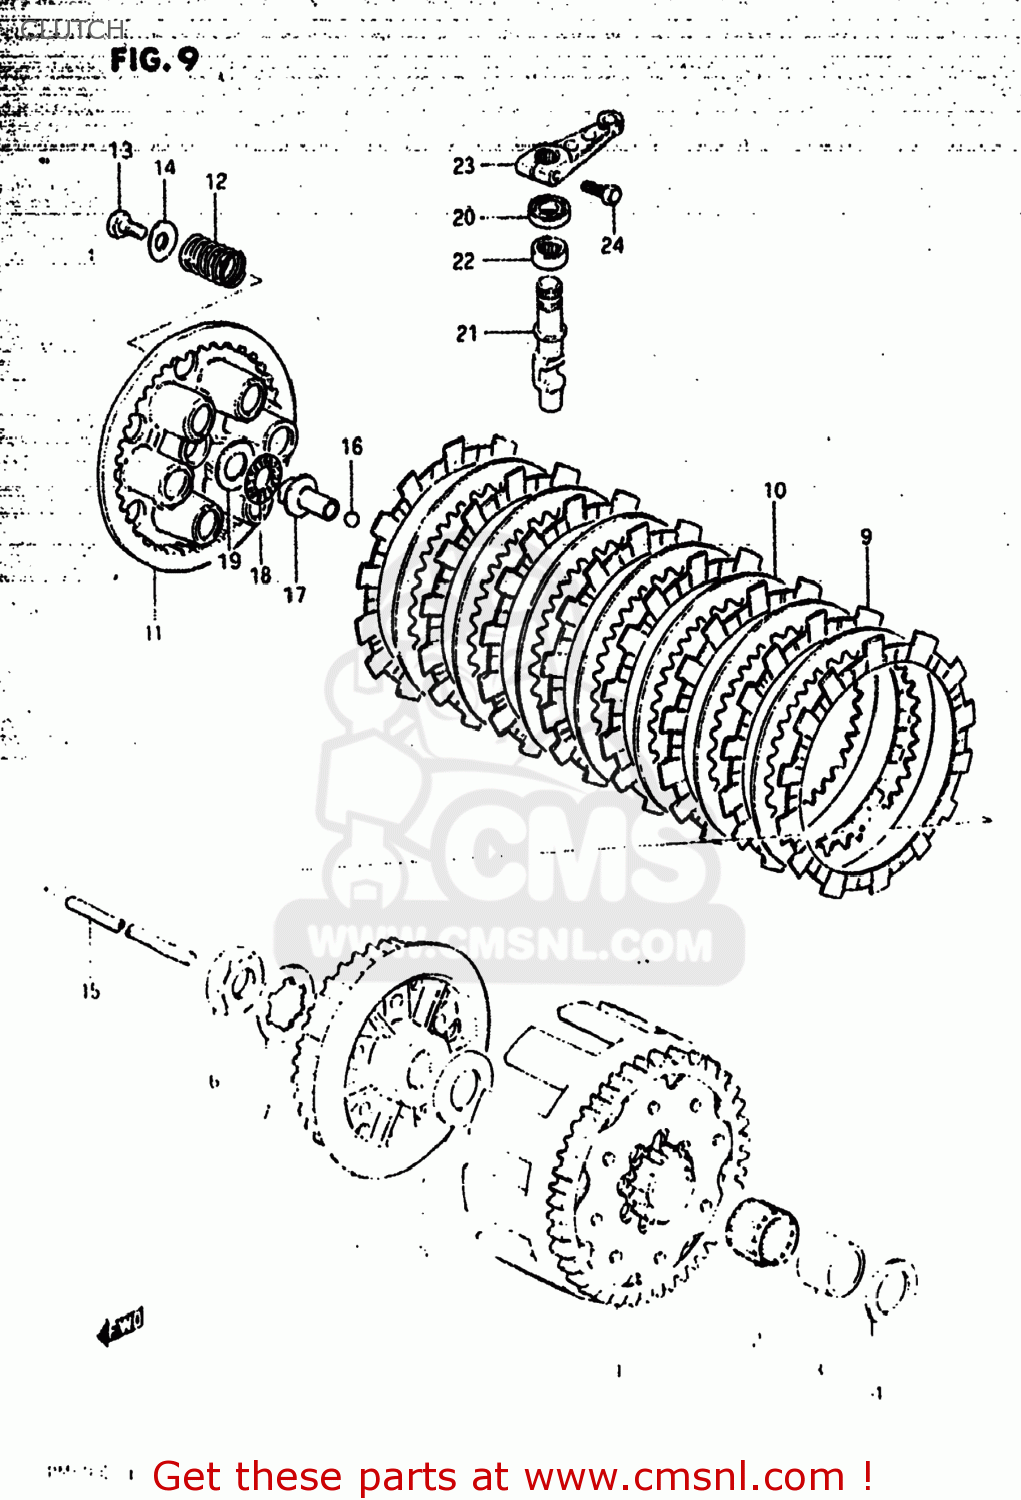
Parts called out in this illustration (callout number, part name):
1	GEAR ASSEMBLY,PRIMARY DRIVE
2	BEARING(28X33X27)
3	SPACER(22X28X27)
4	WASHER
5	HUB,CLUTCH SLEEVE
6	NUT
7	WASHER,LOCK
8	WASHER
9	PLATE,CLUTCH DRIVE (MCA)
10	PLATE,CLUTCH DRIVEN (NAS)
11	DISC,CLUTCH PRESSURE
12	SPRING
13	BOLT, UPPER
14	WASHER
15	ROD,CLUTCH PUSH
16	BALL
17	PIECE,CLUTCH PUSH
18	BEARING(15X28X2)
19	WASHER
20	SEAL,OIL(12X19X5)
21	SHAFT,CLUTCH RELEASE C
22	BEARING(12X19X12)
23	ARM,CLUTCH RELEASE
24	BOLT
